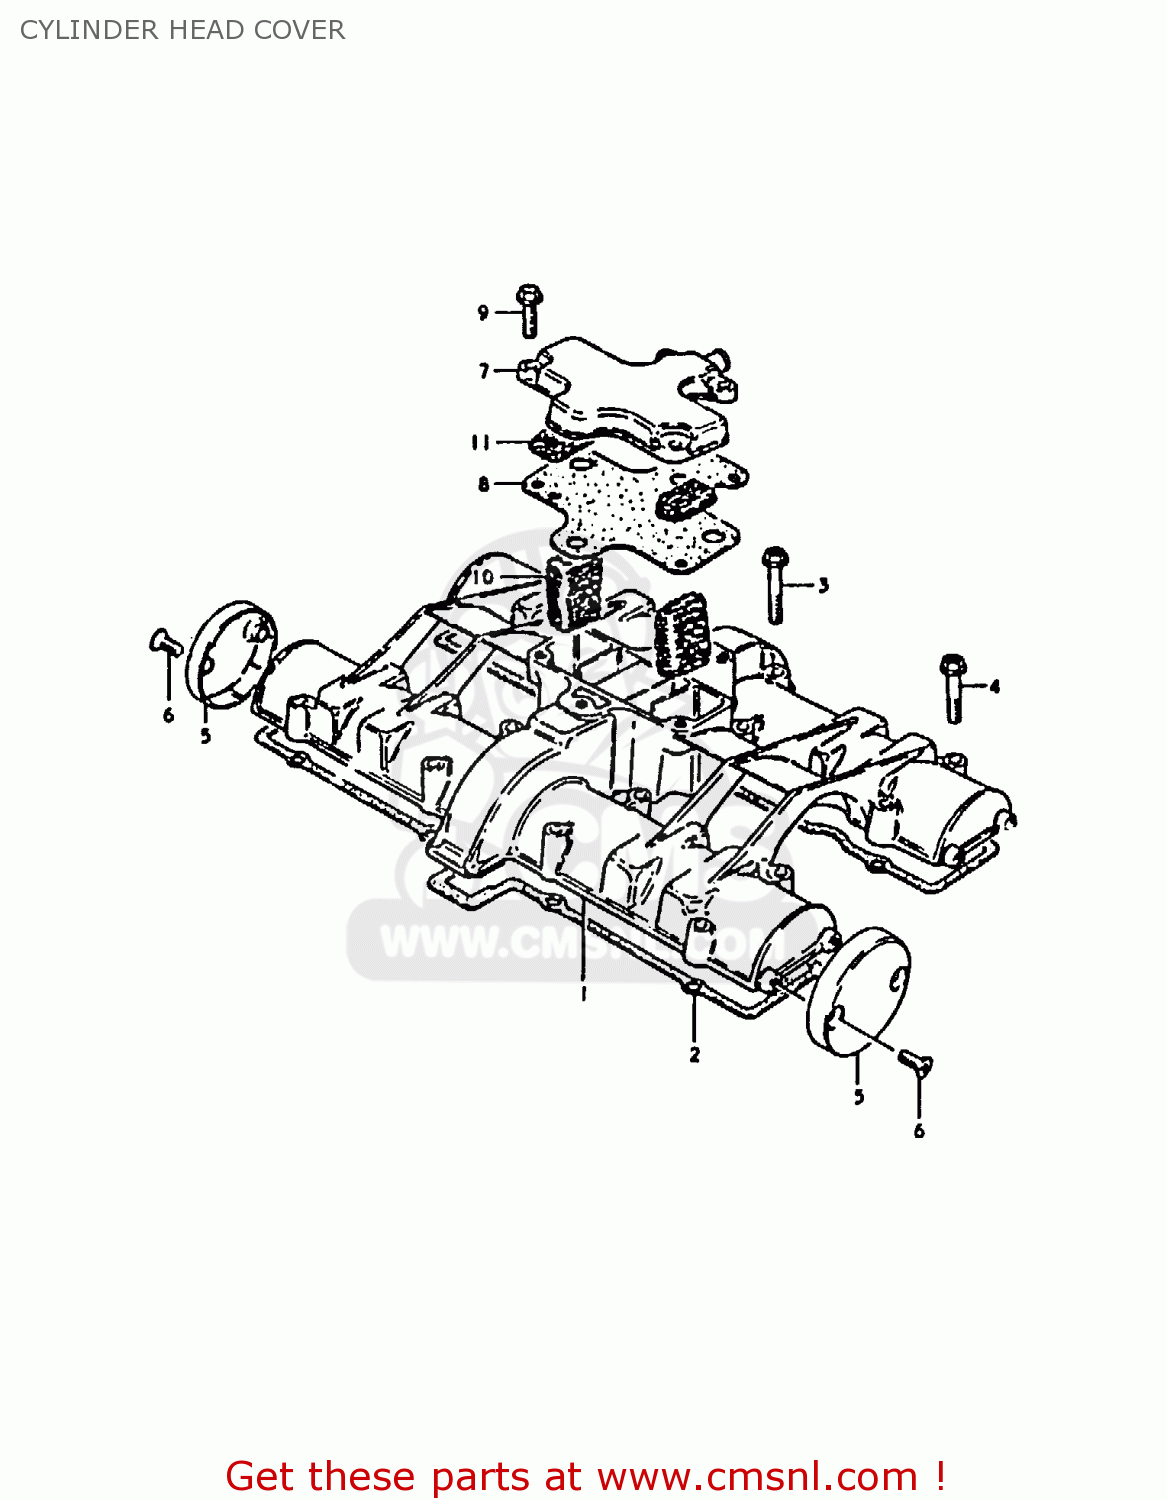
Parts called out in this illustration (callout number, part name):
1	COVER,CYLINDER HEAD
2	GASKET,CYLINDER HEAD COVER (MCA)
3	BOLT
4	BOLT 6X35
5	CAP,CYLINDER HEAD COVER
6	SCREW
7	COVER,BREATHER
8	GASKET (MCA)
9	BOLT
10	COVER,BREATHER
11	SEPARATOR,OIL BREATHER
